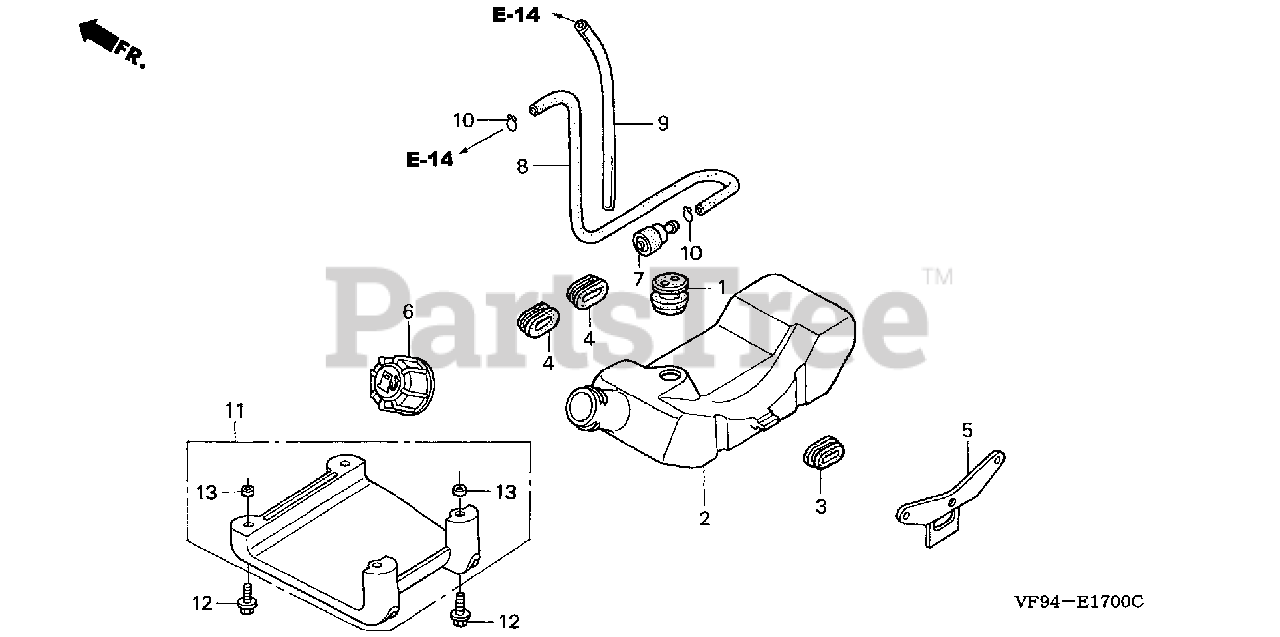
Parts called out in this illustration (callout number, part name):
1	GROMMET, FUEL TUBE
2	TANK, FUEL
3	RUBBER A, TANK MOUNTING
4	RUBBER B, TANK MOUNTING
6	CAP ASSY., FUEL TANK
7	FILTER, FUEL
8	TUBE, FUEL
9	TUBE, FUEL RETURN
10	CLIP, TUBE
11	GUARD, TANK
12	BOLT, FLANGE (5X14) (CT200)
13	COLLAR, TOP COVER
